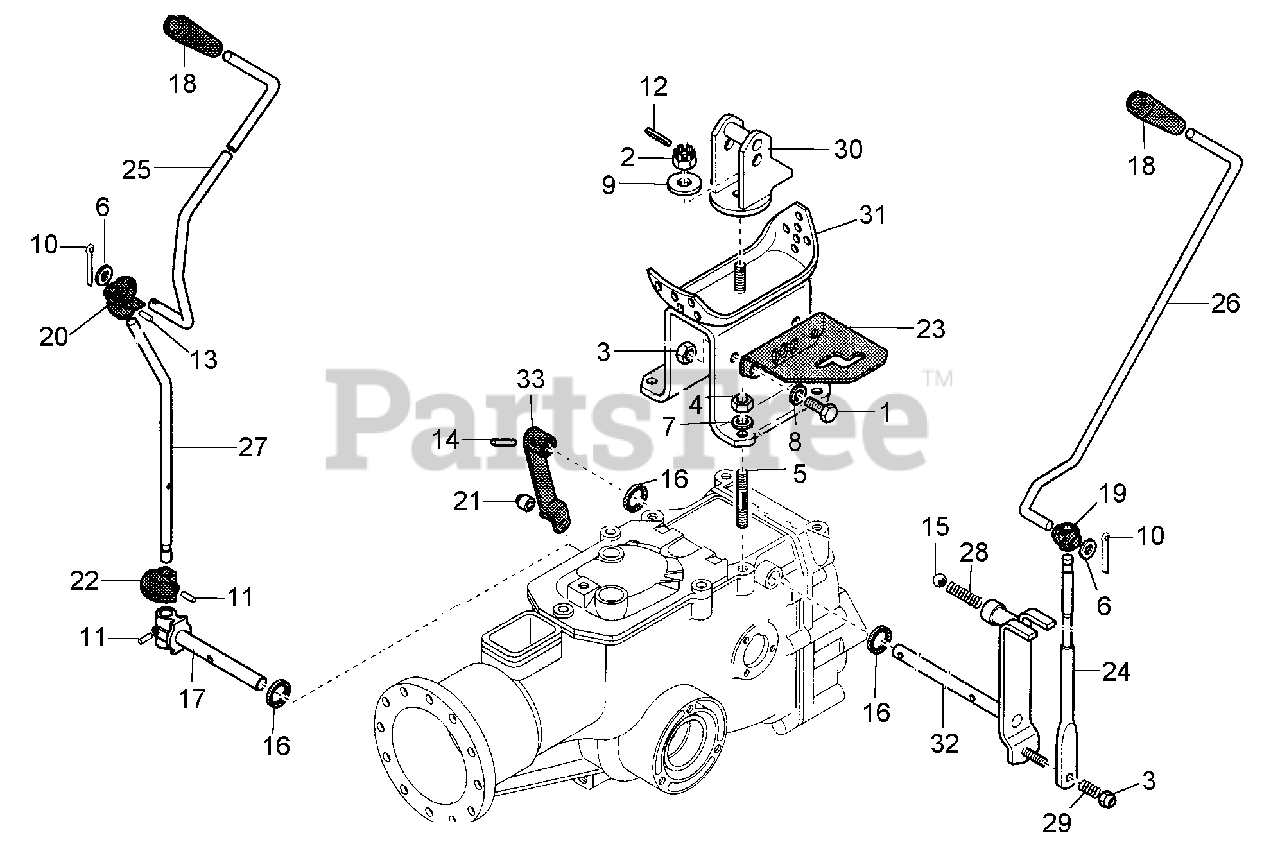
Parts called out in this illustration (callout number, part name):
1	SCREW, M8X20
2	NUT, CASTLE, M12
3	NUT, SELF LOCKING, M8
5	STUD, M8X38X14X20
6	WASHER, M10.5
7	SUPER WASHER
8	WASHER, WAVE
9	LOCK WASHER, M13
11	PIN, LOCKING, M4X20
12	PIN, LOCKING, M3X22
13	PIN, LOCKING, M4X24
14	LOCKING PIN, 6X20 SPIRAL
15	BALL, 15/32"
16	OIL SEAL, 14X22X4
19	ARTICULATOR
20	PTO ARTICULATION
21	PTO LOCKOUT RING
22	PTO STOP RING
23	GEAR SELECTOR, 710
24	SPEED CONTROL LEVER
25	PTO CONTROL ROD, ELECTRIC START
26	SPEED CONTROL ROD, 710, ELECTRIC START
27	PTO CONTROL LEVER
30	HANDLE BAR SUPPORT
31	HANDLE BAR ANCHOR
32	SPEED CONTROL LEVER, 710
33	PTO LOCKOUT LEVER, 710
